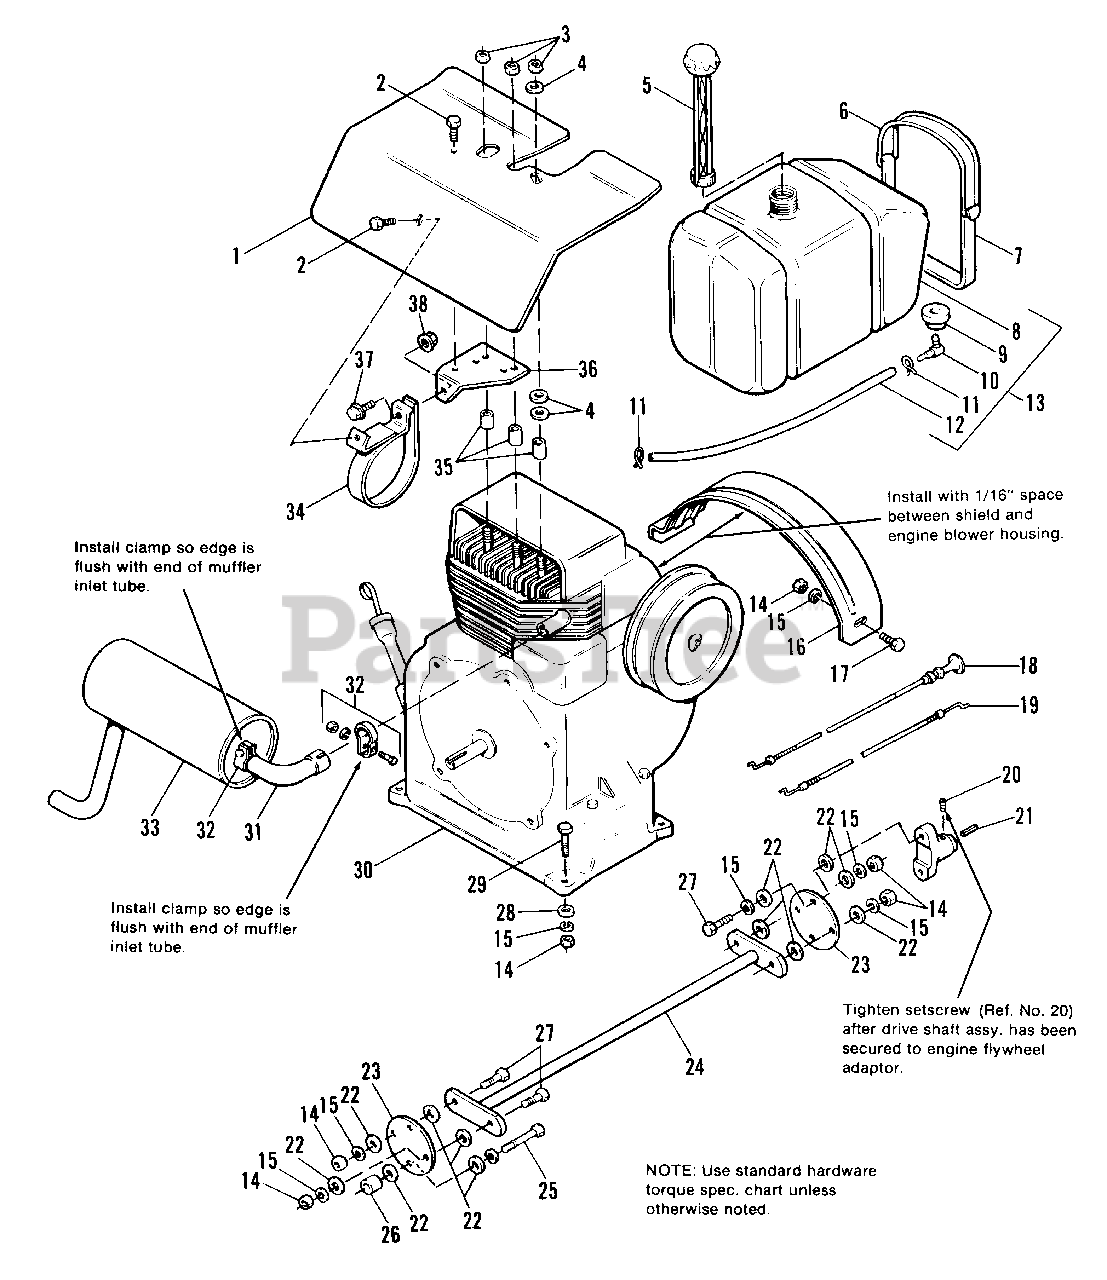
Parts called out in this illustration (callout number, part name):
1	SHIELD, Heat
2	SCREW, Hex, Taptite, 1/4-20 x 1/2
3	LOCKNUT, Hex, Jam, 3/8-16
5	CAP, Fuel Tank
6	STRAP, Fuel Tank
7	STRAP, Tank
11	CLAMP, Hose
13	TANK ASSY., Fuel
14	NUT, Hex, Full, 3/8-16
15	LOCKWASHER, 3/8
17	CAPSCREW, Hex Hd., 3/8-16 x 3/4
18	CONTROL, Choke
19	CONTROL, Throttle
20	SETSCREW, 3/8-24 x 3/8
21	KEY, Drive Shaft
22	WASHER, Special
24	SHAFT ASSY., Drive
25	CAPSCREW, Hex Hd., 3/8-16 x 2-1/4
27	CAPSCREW, Hex Hd., 3/8-16 x 1-1/4
28	WASHER, Plain, 3/8
29	CAPSCREW, Hex Hd., 3/8-16 x 1-1/2
30	ENGINE, 12 HP Kohler
31	ELBOW, Exhaust
32	CLAMP, Muffler
33	MUFFLER, Exhaust
34	STRAP ASSY., Muffler
36	SUPPORT, Muffler
37	CAPSCREW, Hex, Whiz, Flange, 5/16-18 x 1-1/2
38	NUT, Hex, Flange, 5/16-18
